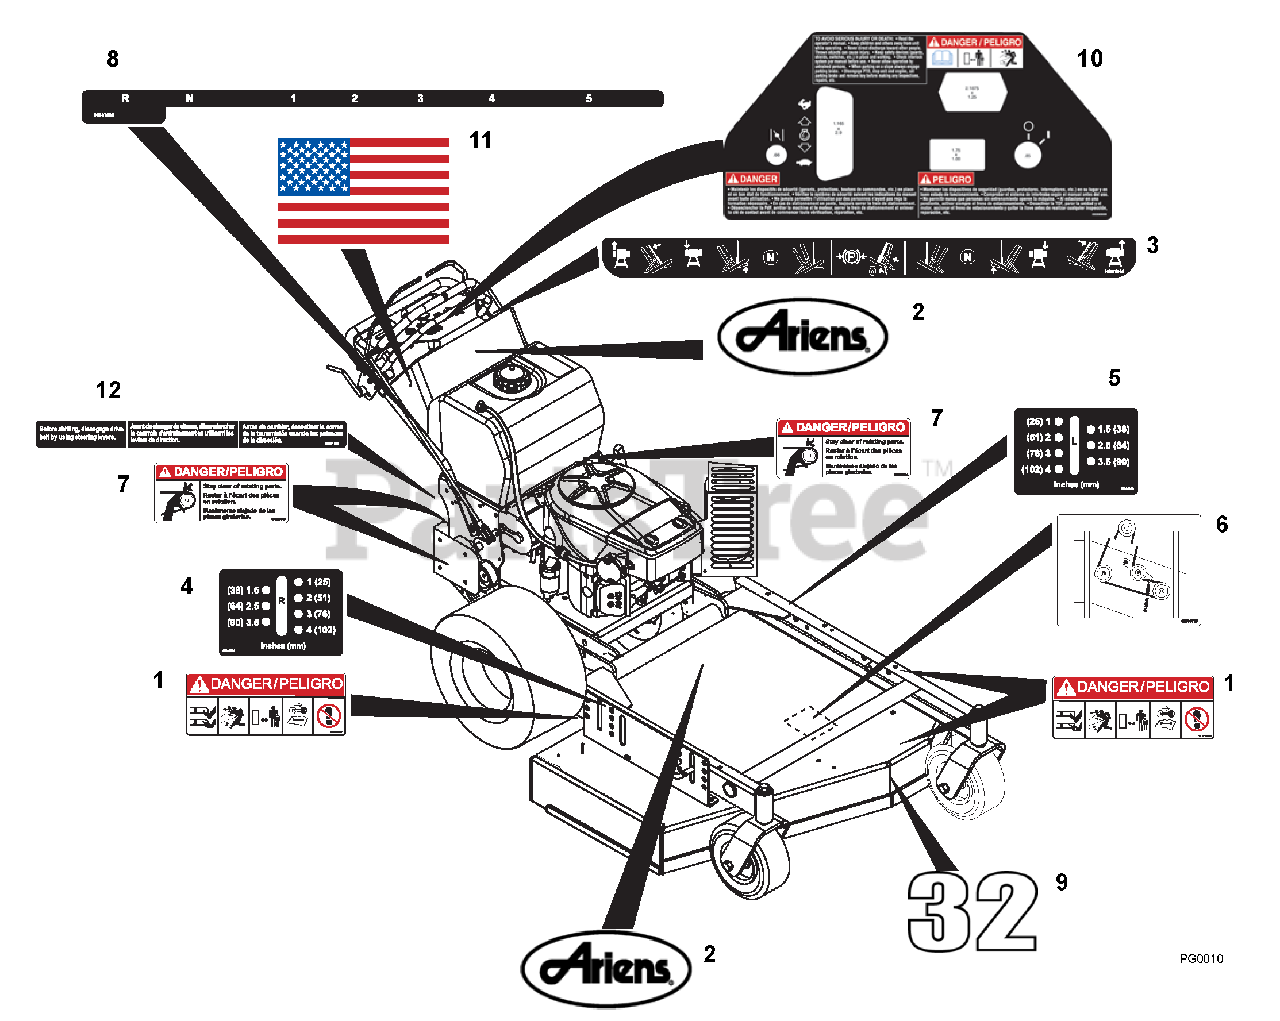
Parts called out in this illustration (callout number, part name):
1	DECAL, MOWER PAN DANGER
2	DECAL, ARIENS
3	DECAL-STEER LEVERS-GEAR-ERGO
4	DECAL-HEIGHT OF CUT-FIXED - RH
5	DECAL-HEIGHT OF CUT-FIXED - LH
6	DECAL-BELT DIAGRAM-2 SPINDLE
7	DECAL-DANGER-BELT ROTATING
8	DECAL-SHIFT LEVER
9	DECAL, 32
10	DECAL - CONTROL GR15 - ERGO
11	DECAL, AMERICAN FLAG
12	DECAL - DECLUTCH - GEAR
